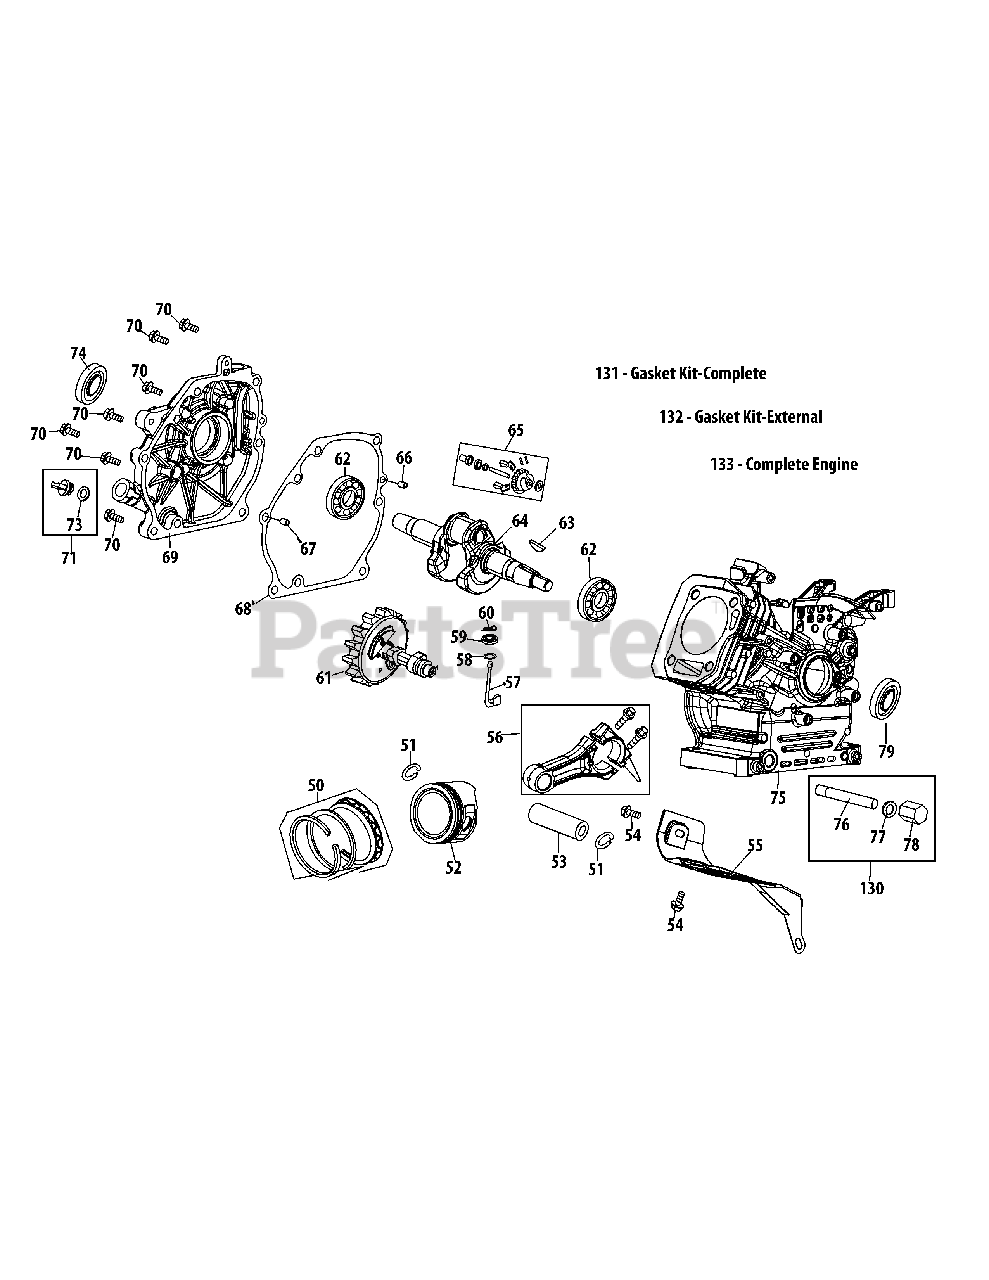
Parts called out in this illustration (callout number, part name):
50	Piston Ring Set
51	Piston Pin Snap Ring
53	Piston Pin
54	Bolt - M6 X 12 Zin
55	Shield - Air
56	Connecting Rod Assembly
57	Governor Shaft
59	Governor Seal
60	Cotter Pin
61	Camshaft Assembly
63	Key:Flywheel
64	Crankshaft Kit
65	Governor Gear/Shaft
66	Pin-Dowel
67	Dowl Pin 9X14
68	Crankcase Cover Gasket
69	Crankcase Cover
69	Crankcase Cover Kit
71	Oil Fill Plug Assembly
73	O-Ring 15.8 X 2.5
74	Oil Seal
75	Crankcase Kit
75	Shortblock Assembly
76	Oil Drain Pipe
77	Washer
78	Bolt - Drain Plug
79	Oil Seal
130	Oil Drain Assembly
131	Gasket Kit-Complete
132	Gasket Kit-External
133	Complete Engine
